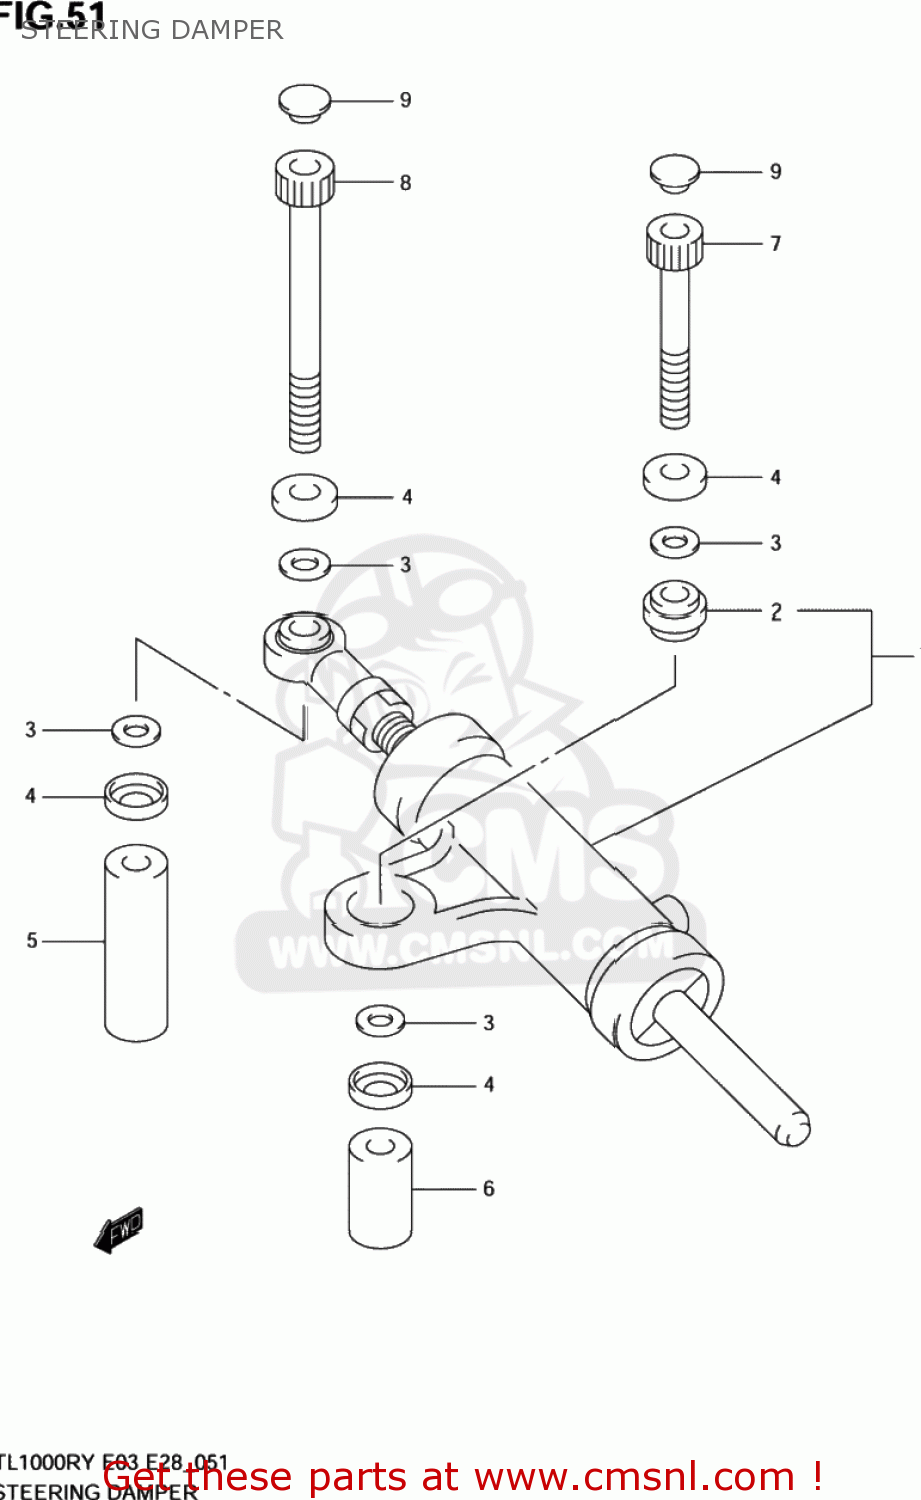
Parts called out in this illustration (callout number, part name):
1	DAMPER,STEERING
2	BEARING(8X17.5X11)
3	SHIM(8X12X0.8)
4	5
5	SPACER,STEERING DAMPER
6	SPACER,STEERING DAMPER
7	BOLT
8	BOLT
9	CAP(OD:11)
